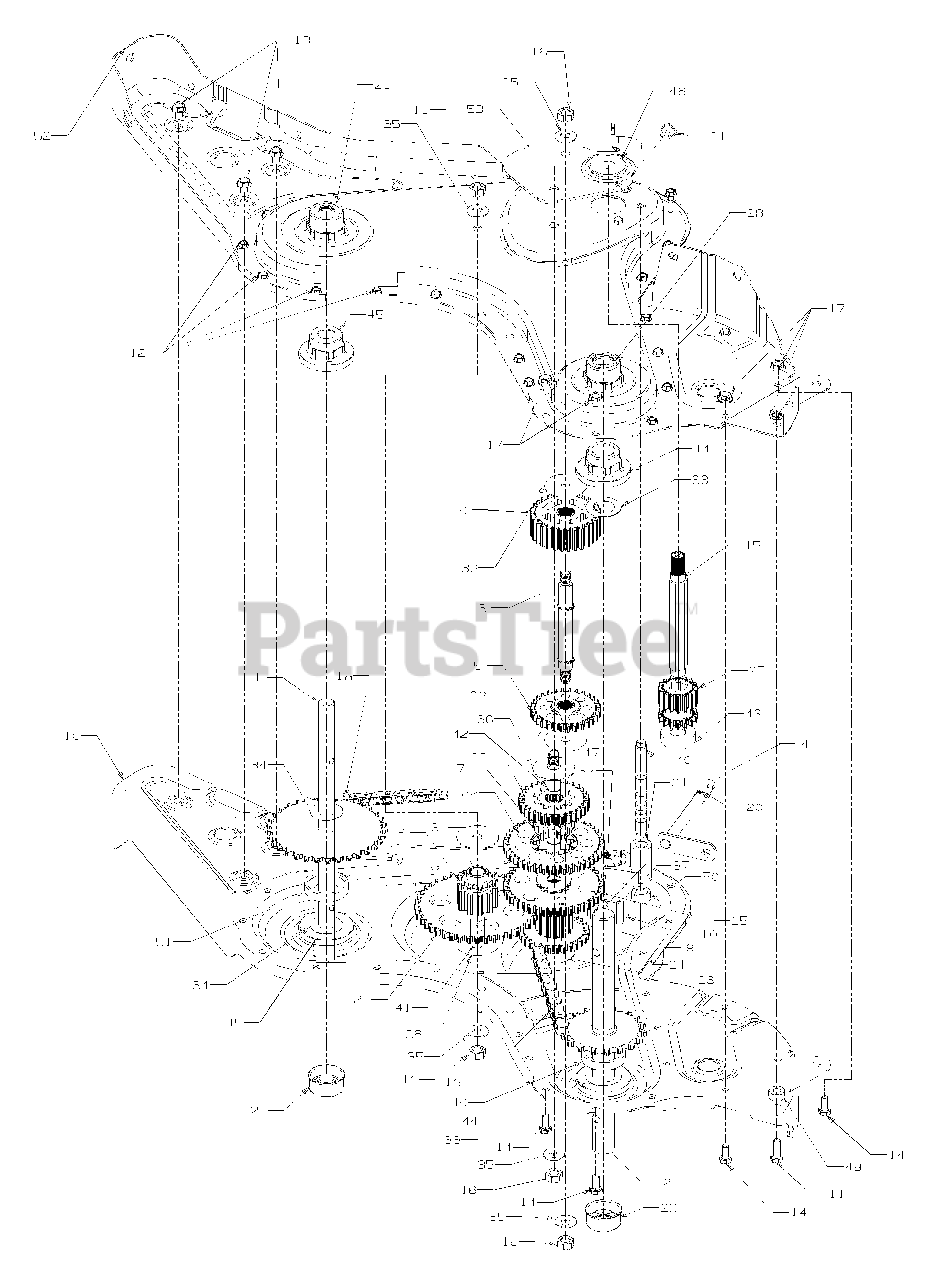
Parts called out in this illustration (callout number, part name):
1	Wheel Shaft Ass'y: 33T
2	Tine Shaft Ass'y: 18T
3	Jack Shaft Ass'y
4	Input Shaft Ass'y
5	Rev. Idler Gear Ass'y: 30T
6	Ftine Idler Gear Ass'y: 30T
7	Tine Input Sprocket Ass'y: 9T
8	Wheel Input Sprocket Ass'y:10T
9	Gear Ass'y: 11 T
10	R.H. Housing Ass'y
11	Hex Bolt 5/16-18 x 1" Lg.
12	Hex S-Tap Scr. 1/4- 20 x .5"
13	Hex S-Tap Scr. 5/16-18 x .625"
14	Hex Bolt 5/16-18 x .75"
15	Input Shaft
16	Hex Nut 7/16-20
17	Flange Nut 5/16-18
18	#420 Chain 1/2 Pitch x 50 Links
19	#50 Chain 5/8 Pitch x 54 Links
20	Snap Ring
21	Shifting Fork
22	Spur Gear 44T
23	Spur Gear 30T
24	Spur Gear 30T
25	Spur Gear 44T
26	Spur Gear 44T
27	Spur Gear 16T
28	Seal 1.0 Shaft
29	Seal .75 Shaft
31	Taper Cap Ring
32	Compression Spring .50" Lg.
33	Thrust Wash. 1.03" I.D. x 1.62"
34	Fl-Wash.76" I.D. x 1.5" O.D.
35	Bell-Wash.45" I.D. x 1.0"
36	Thrust Wash. .445 x 1.92 x .060
37	Fl-Wash 635" I.D. x 1.59 O.D.
40	Detent Shaft 1/2" Dia.
41	Jack Shaft .625 x 2.385
42	Jack Shaft .625 x 5.0
43	Ball Bearing
44	Flange Bearing 1.0 x 2.5 x 1.38
45	Flange Bearing .75 x 2.5 x 1.38
46	Ball Bearing. 6692 x 5745 x
47	Detent Ball .250
48	Spacer.315
49	Spacer 1.0 I.D x 2.0 O.D. x .440
50	Spacer.505 I.D. x .88 O.D. x
51	Spacer.75 x 2.0 x .50
52	L.H. Chain Case Ass'y
53	Gear Positioner Bracket
